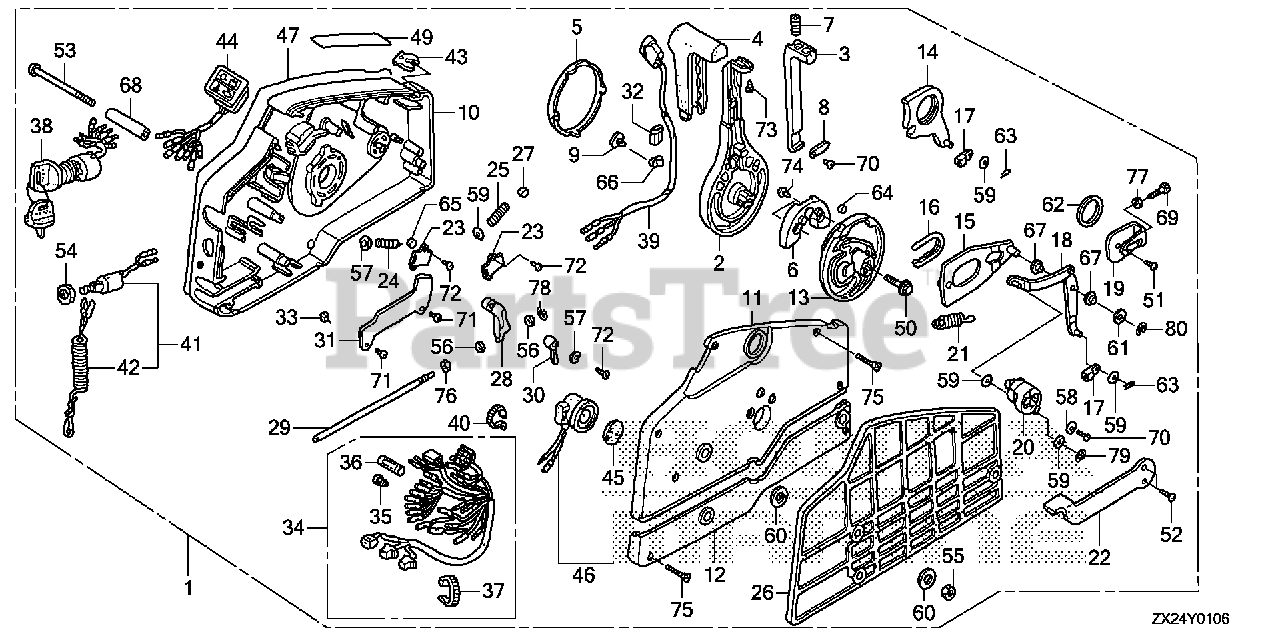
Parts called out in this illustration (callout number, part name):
1	BOX ASSY., REMOTE CONTROL (NHK MEC)
1	BOX ASSY., REMOTE CONTROL (TROLLING CONTROL)(NHK MEC)
2	HANDLE, REMOTE CONTROL
3	LEVER, HANDLE LOCK
4	GRIP, REMOTE CONTROL HANDLE
5	CAP, HANDLE
6	BLOCK, NEUTRAL LOCK
7	SPRING, REMOTE CONTROL HANDLE
8	PLATE, LEVER SETTING
9	CLAMP, HARNESS
10	HOUSING, REMOTE CONTROL BOX (A)
11	HOUSING, REMOTE CONTROL BOX (B)
12	HOUSING, REMOTE CONTROL BOX (C)
13	WHEEL, CONTROL
14	ARM, SHIFT LINK
15	PLATE, SLIDING
16	COLLAR, SLIDING PLATE
17	PIVOT, SHIFT
18	ARM, LINK JOINT
19	BRACKET, LINK JOINT
20	WHEEL, ACCELERATOR
21	SPRING, ACCELERATOR WHEEL
22	LEVER, IDLE
23	PLATE, SPRING SETTING
24	SPRING, SHIFT CLICK
25	SPRING, CHOKE RETURN
26	SPACER, REMOTE CONTROL BOX
27	SPACER, CLICK SPRING
28	BLOCK, THROTTLE FRICTION
29	BOLT, FRICTION
30	SPACER, NEUTRAL SWITCH
31	CLAMP, POWER TILT CORD
32	PIPE, HARNESS GUIDE
33	SPACER, CABLE CLAMP
34	CABLE ASSY., REMOTE CONTROL (B)
35	PLUG, CONNECTOR (INNER)
36	PLUG, CONNECTOR (OUTER)
37	TIE, CABLE (2.4X92) (NATURAL)
38	SWITCH ASSY., COMBINATION
39	SWITCH ASSY., POWER TRIM-TILT
40	BAND (BLACK 3.5X140)
41	SWITCH ASSY., EMERGENCY STOP
42	WIRE, EMERGENCY
43	CLIP, EMERGENCY LOCK
44	LAMP ASSY., INDICATION
45	PLATE, TURN SIGNAL BUZZER
46	BUZZER, WARNING
47	PLATE, REMOTE CONTROL (COUTION COLOR=RED & YELLOW)
49	MARK, FAST IDLE
50	BOLT, FLANGE (8X35)
51	SCREW, PAN (6X10)
52	SCREW, FLAT (5X12)
53	SCREW (6X95)
54	NUT, HEX. (16MM)
55	NUT, HEX. (6MM)
56	WASHER, PLAIN (4MM)
57	WASHER, PLAIN (5MM)
58	WASHER, PLAIN (5MM)
59	WASHER, PLAIN (6MM)
60	WASHER (6MM)
61	WASHER, PLAIN (8MM)
62	WASHER (28MM)
63	PIN, LOCK (6MM)
64	PIN (6X6)
65	ROLLER, CLICK
66	CLIP, WIRE HARNESS (6.3MM)
67	COLLAR, LINK JOINT
68	COLLAR, DISTANCE (6X10X43.5)
69	BOLT, HEX. (5X16)
70	SCREW, PAN (5X10)
71	SCREW, TAPPING (5X8)
72	SCREW, TAPPING (5X10)
73	SCREW, TAPPING (5X12)
74	SCREW, TAPPING (6X16)
75	SCREW, TAPPING (5X25)
76	NUT, HEX. (6MM)
77	NUT, HEX. (5MM)
78	E-RING (3MM)
79	E-RING (4MM)
80	E-RING (7MM)
